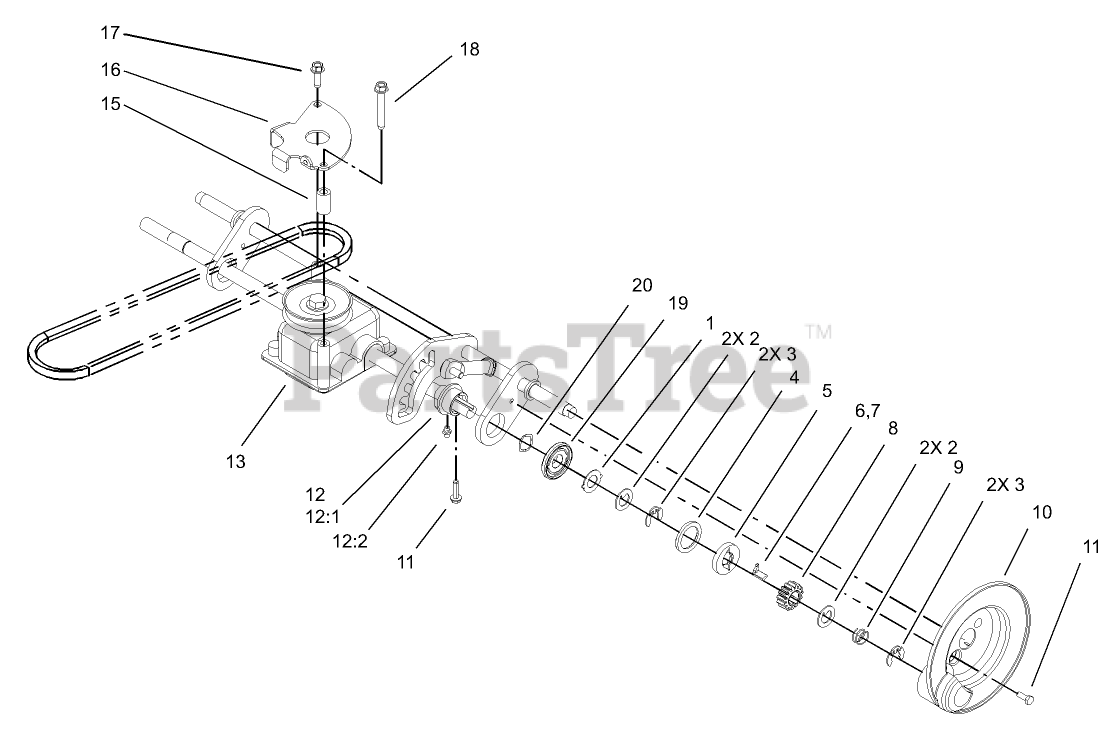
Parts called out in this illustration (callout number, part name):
1	WASHER-ARM, PIVOT
2	WASHER-THRUST, KEYED
3	RING-RETAINING,CLIP
4	RING-FRICTION
5	WASHER-CLUTCH
6	KEY-ROCKING, RH
7	KEY-ROCKING, LH
8	GEAR-PINION
9	SPRING-COMPRESSION
10	COVER-GEAR
11	SCREW-TAPTITE
12	BUSHING ASM
12:2	FITTING-GREASE
13	GEAR CASE ASM
15	BUSHING-PLATE, ACTUATOR
16	GUIDE-TRANSMISSION
17	SCREW-HWHTF
18	SCREW-HWHTF
19	RETAINER-RING
20	WASHER-WAVE
